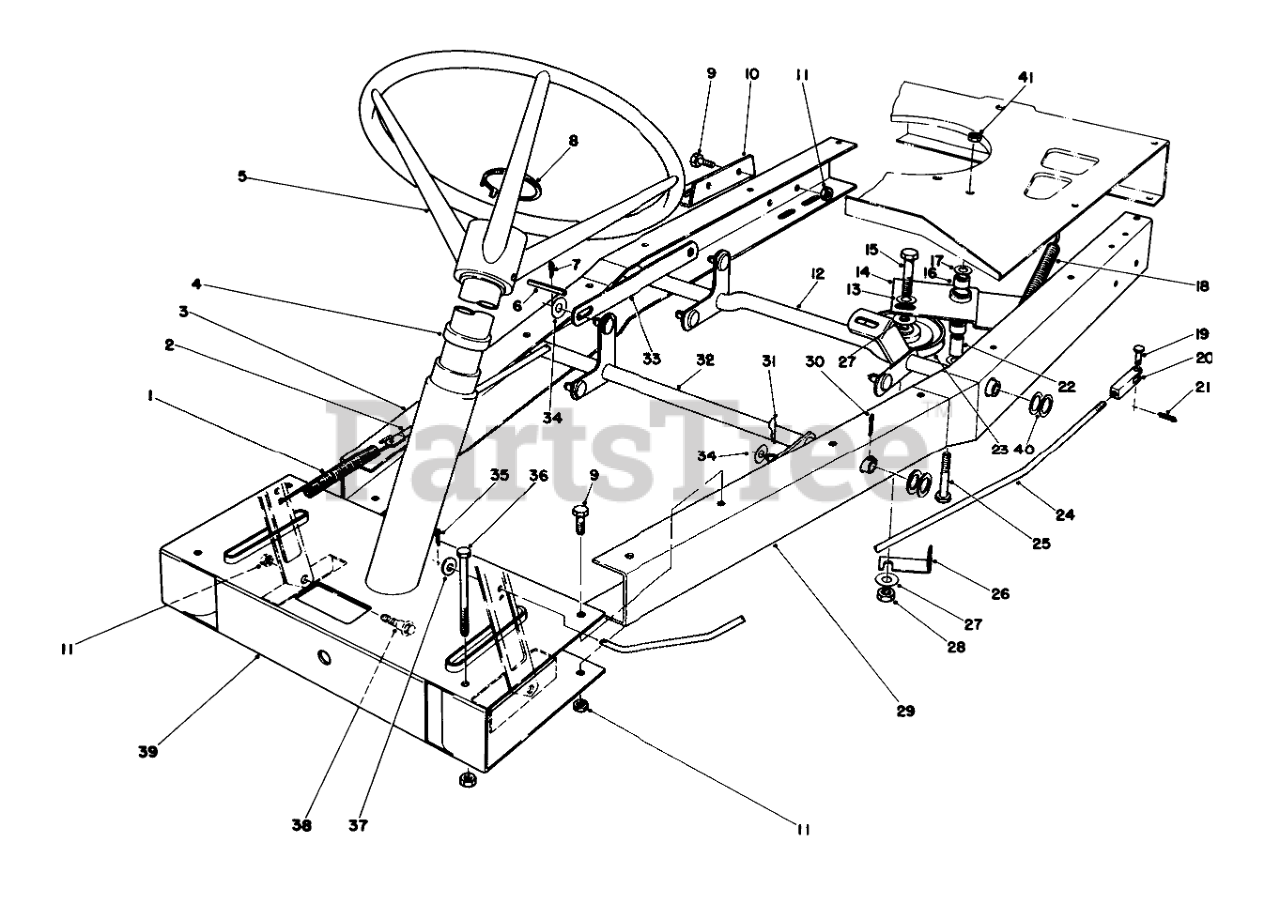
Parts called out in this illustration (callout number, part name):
1	BRAKE TENSION SPRG O
2	Brake Rod
3	Frame-Channel R.H.
4	STEERING TUBE WA BO
5	Steering Wheel (Incl. Ref. #8)
6	PIN-ROLL
7	PIN-COTTER
8	Cap-Steering Wheel
9	SCREW-HH
10	Mount-Axle Brg.
11	NUT-LOCK, NI
12	REAR HT ADJ WA B
13	WASHER-FLAT
14	Traction Idler (Incl. Ref. #16)
15	SCREW-HH
16	BUSHING
17	WASHER-PLAIN
18	Clutch Tension Spring
19	PIN-CLEVIS
21	PIN-COTTER
22	PIVOT SPACER
23	PULLEY-IDLER
24	Rod-Clutch
25	SCREW-HH
26	RETAINER-BELT
27	WASHER-FLAT
28	NUT-LOCK, SIDE
29	LH FRAME CHANNEL B
30	PIN-COTTER
31	PIN-COTTER
32	FRONT LIFT WA B
33	Linkage-Height Adj.
34	WASHER-FLAT
35	PIN-COTTER
36	SCREW-HH
37	WASHER-FLAT
38	SCREW-SHOULDER
39	Front Frame
40	WASHER-FLAT
41	NUT-HEX
